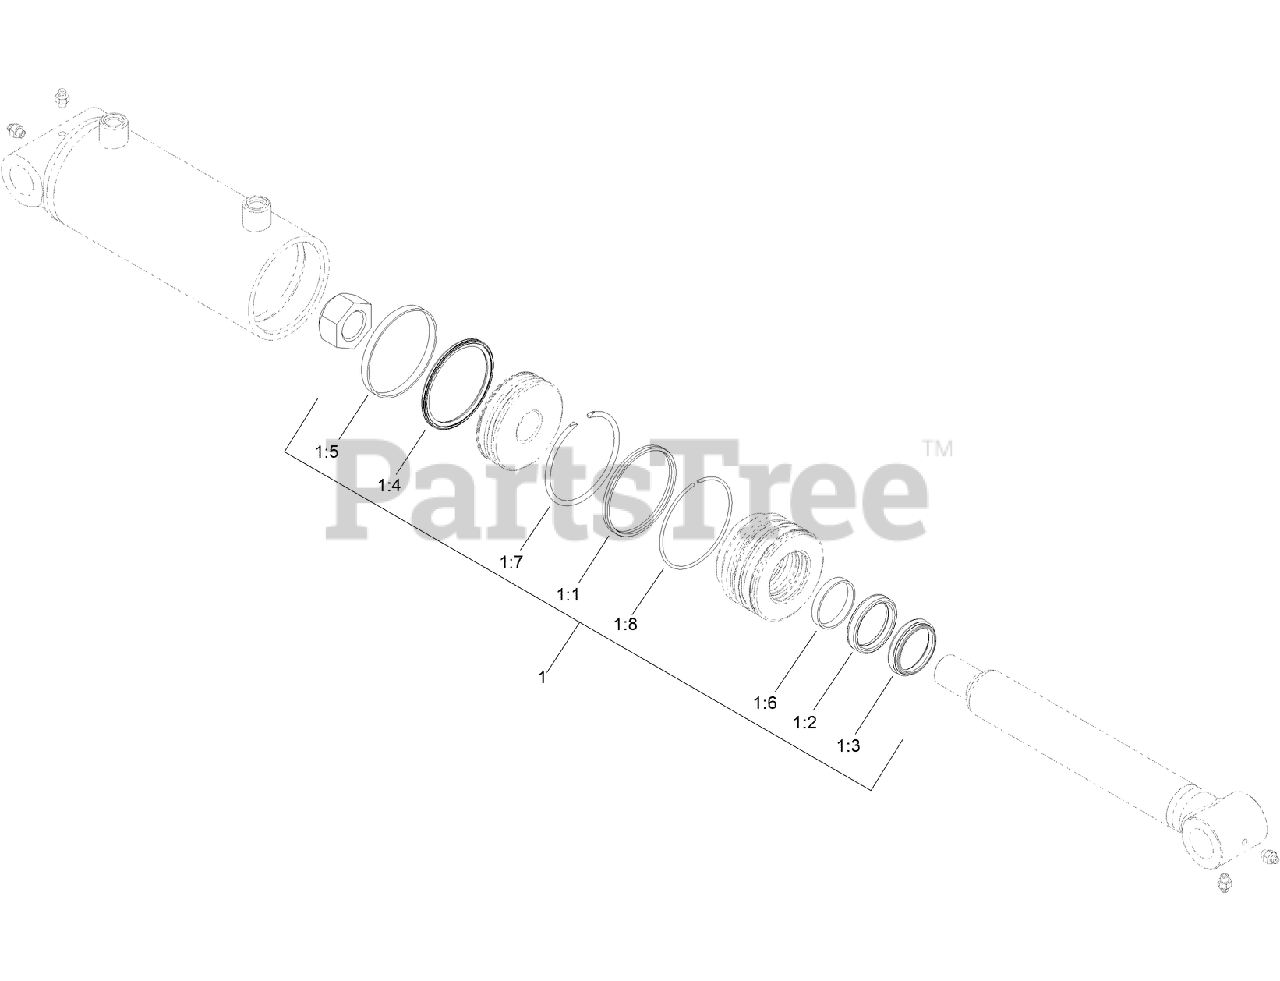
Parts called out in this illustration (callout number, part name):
1	SEAL REPAIR KIT
1:1	SEAL-DUAL
1:2	Deck ASM
1:3	Deck ASM
1:4	Deck ASM
1:5	RING-wear, piston
1:6	RING-WEAR, ROD
1:7	RING-RETAINING, INTERNAL
1:8	RING-RETAINING, EXTERNAL
